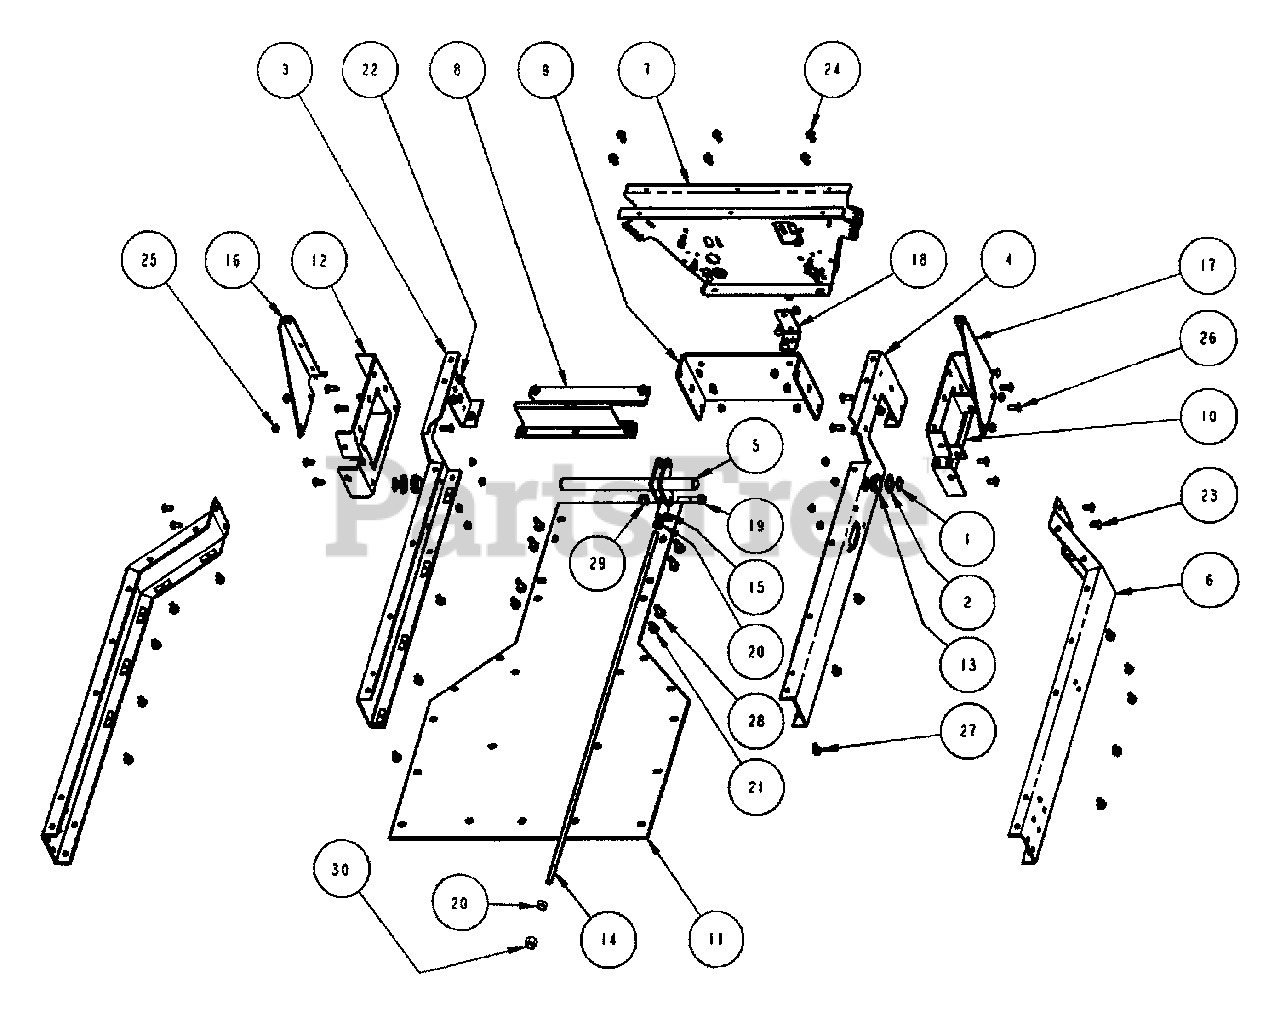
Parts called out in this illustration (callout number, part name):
1	EXTERNAL RETAINING RING 1 INCH
2	BUSHING
3	WELDMENT, INNER L.H. FRAMERAIL
4	WELDMENT, INNER R.H. FRAMERAIL
5	WELDMENT, LOWER CVT BRAKE
6	WELDMENT, OUTER CVT FRAME
7	WELDMENT, SUSPENSION SUPPORT
8	WELDMENT, STEERING BRKT.
9	END, FRAME
10	SUSPENSION PIVOT, RH
11	FRAME STIFFENER
12	SUSPENSION PIVOT, RH
13	BEARING, 1 IN. ID
14	ROD, UPPER CVT BRAKE
15	ROD END, FEMALE, 1/2-20 YZ
16	SHOULDER, HANDLE PIVOT
17	SUSPENSION GUSSET, RH
18	THROTTLE ANCHOR, FRONT
19	HHCS, 1/2-13 X 2.00 GR5
20	HJN, 1/2-20
21	HFLB, 5/16-18 x.75 BL
22	H NYL, 3/8-16, YZ
23	RHSSNB, 5/16-18 X 3/4 GR5YZ
24	HWST, 5/16-18 X 3/4 YZ
25	FLN 5/16-18 YZ
26	RHSNB 5/16-16 X 1 GR5 YZ
27	HFLB, 5/16-18 X .625 - YZ
28	HFLB 3/8-16 X 1.0 - YZ
29	NUT, 1/2-13, LIGHT, NYLOCK
30	NUT, 1/2-13 HEX NYLOCK
